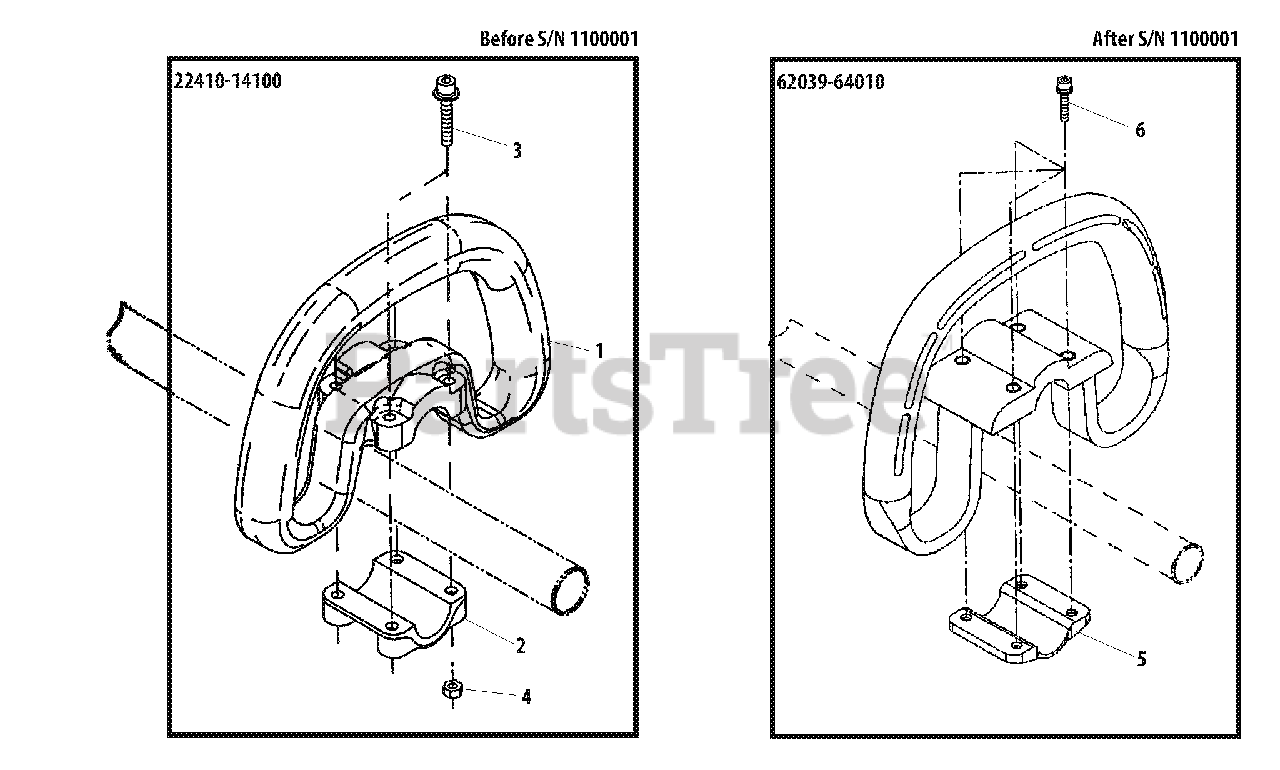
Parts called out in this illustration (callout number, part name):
1	HANDLE - FRONT
2	CAP - LOWER
3	SCREW - 5X30
5	CLAMP - LOWER
6	SCREW - 5X25
A	HANDLE ASSY - FRONT
B	HANDLE ASSY
